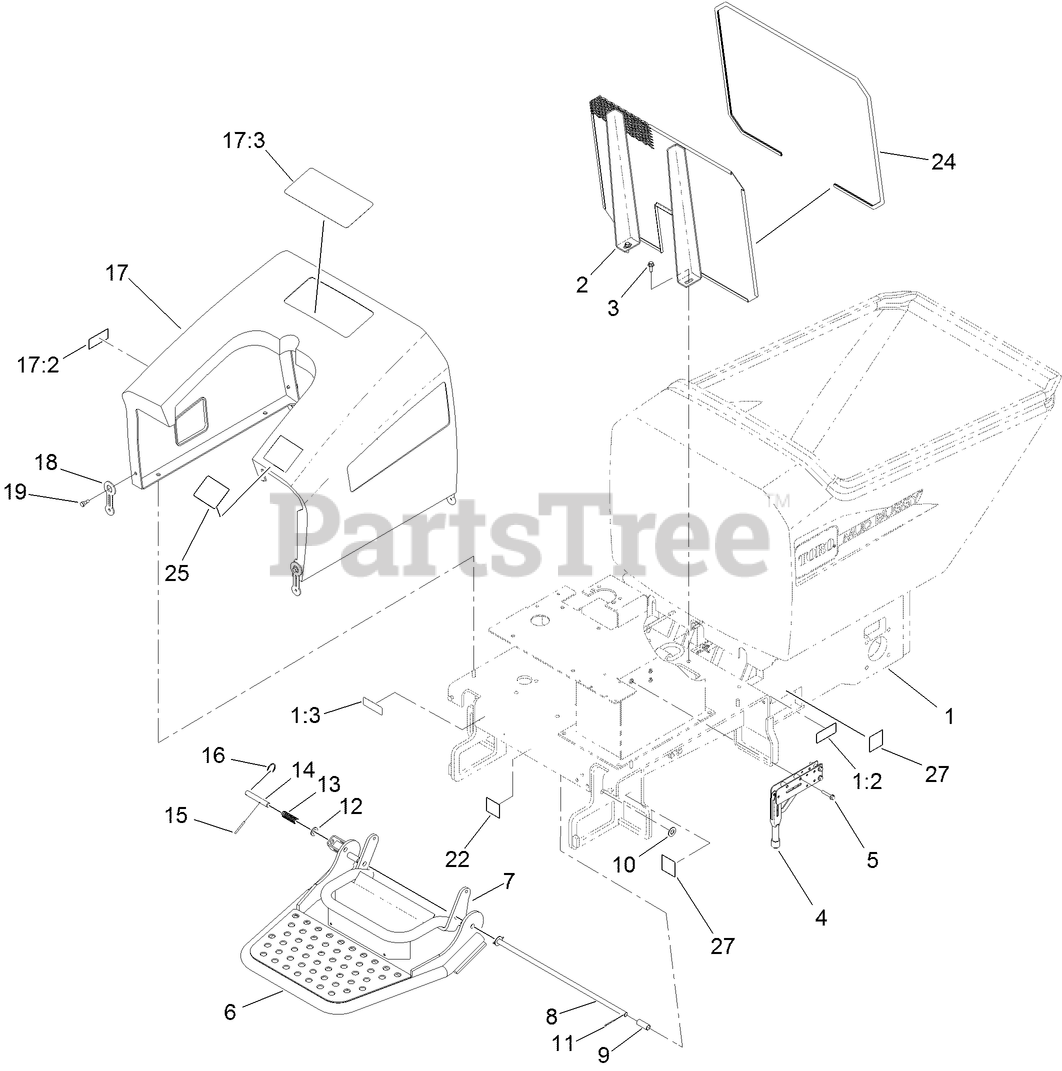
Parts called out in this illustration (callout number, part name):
1	MAIN FRAME ASM
1:2	DECAL-WARNING, CRUSHING
1:3	DECAL-ARRESTOR, SPARK
2	GUARD-SPLASH
3	SCREW-HHF
4	LEVER
5	SCREW-HHF
6	STEP-PLATFORM
7	PEDAL-BRAKE
8	SHAFT-PIVOT, STEP
9	SPACER-BRAKE
10	WASHER-FLAT
11	PIN-COTTER
12	WASHER-FLAT
13	SPRING-COMPRESSION
14	PIN-LOCKOUT, STEP
16	RING-SPLIT
17	ENGINE COWL ASM
17:2	DECAL-SURFACE, HOT
17:3	DECAL-WARNING
18	LATCH-RUBBER
19	SCREW-HSBH
22	DECAL-BRAKE PEDAL
24	TRIM-SPLASH GUARD
25	DECAL-DUMP
27	DECAL-LIFT HERE
